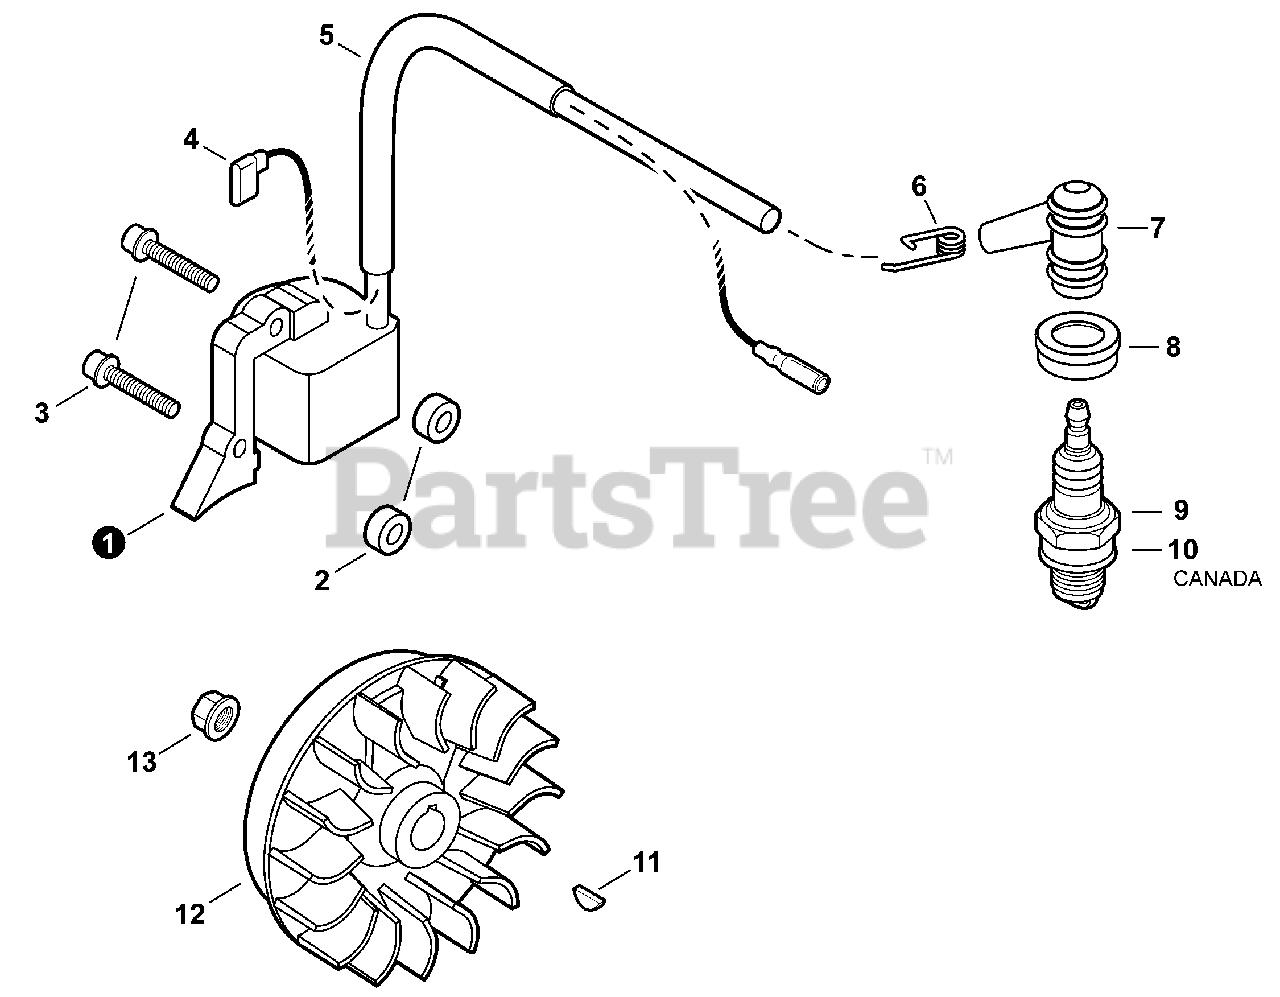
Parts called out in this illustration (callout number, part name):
1	COIL, IGNITION
2	INSULATOR 4.2×11×6
3	BOLT, ADHESIVE M4×24
4	LEAD - IGNITION L= 180
5	TUBE, IGNITION COIL Ø8×L125
6	TERMINAL, SPARK PLUG
7	CAP, SPARK PLUG
8	SEAL, SPARK PLUG
9	SPARK PLUG - BPM8Y
10	SPARK PLUG - BPMR8Y
11	KEY, WOODRUFF 3×10
12	FLYWHEEL
